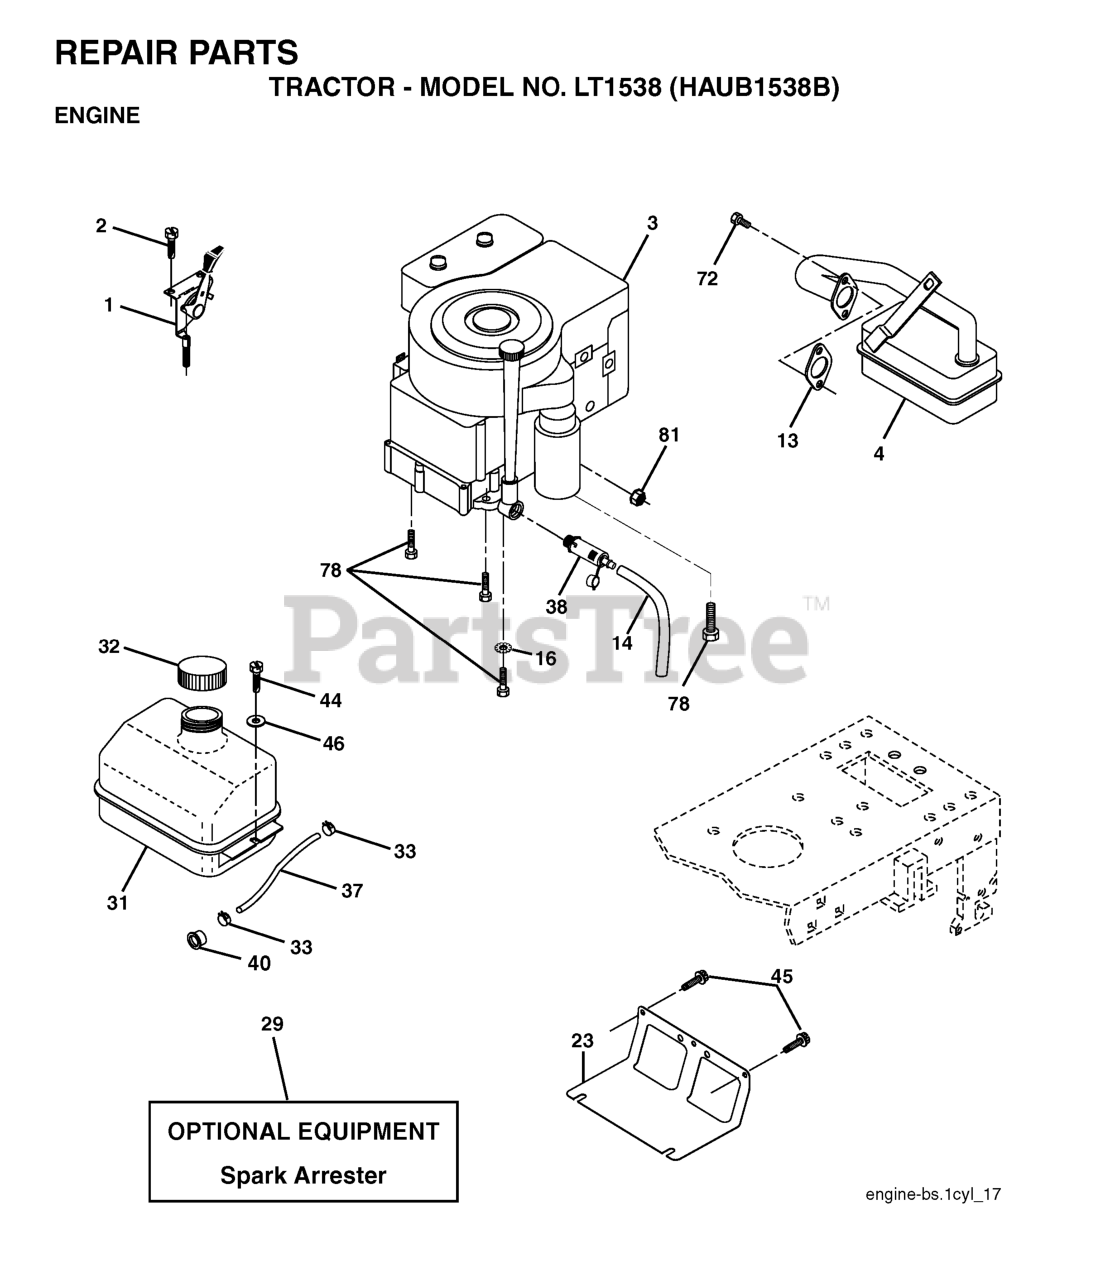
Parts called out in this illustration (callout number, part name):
1	CONTROL.THROTTLE/CHOKE.BLACK
2	SCREW
4	MUFFLER.LT.BRIGGS.14HP.IC/OHV
13	REPL BY 532 27 22-93
14	TUBE, DRAIN OIL ASM.
16	LOCKWASHER
23	SHIELD.BROWNING.DBR.GUARD
29	KIT.SPARK ARRESTOR 794945 B&S
31	TANK.ASM.FUEL.FRONT.W/CAP
32	FUEL CAP
33	HOSE CLAMP
37	LINE.FUEL.20
38	PLUG DRAIN OIL EASY
40	BUSHING.SNAP.NYL.BLK.
44	SCREW HEXWSHR 1/4-20X3/4
45	SCREW, 3/8-16X3/4
72	SCREW.SOCKET.HEAD.5/16-18
78	SCREW.3/8-16
81	NUT
